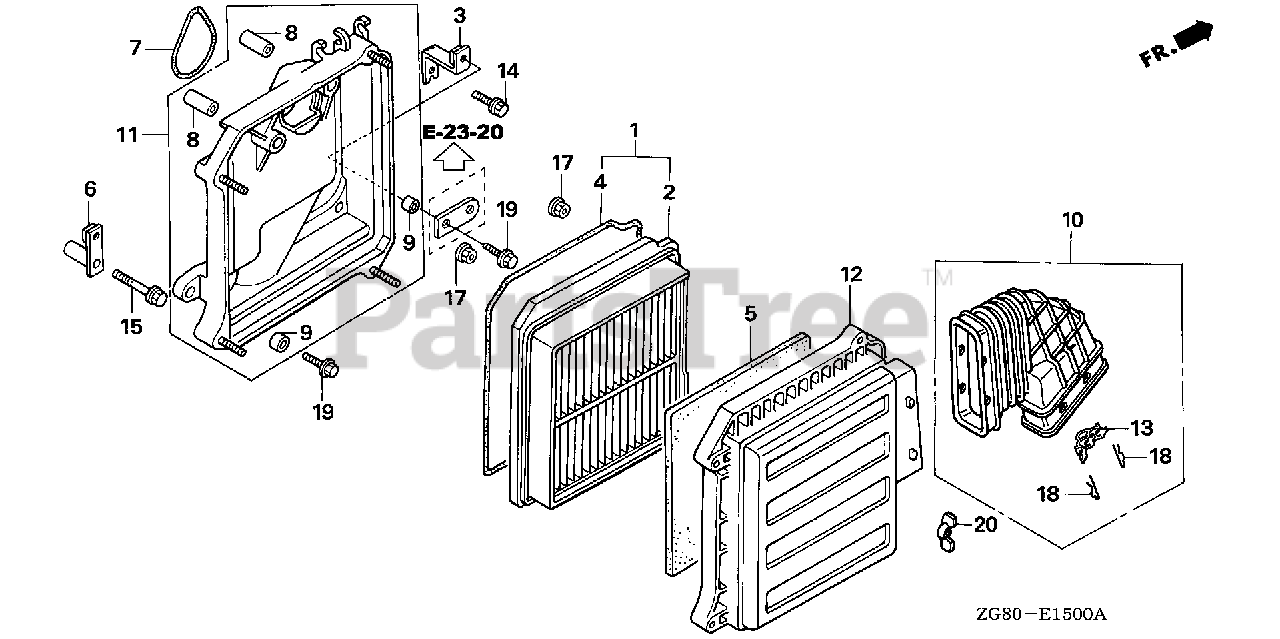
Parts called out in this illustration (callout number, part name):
1	ELEMENT KIT, AIR CLEANER
2	ELEMENT KIT, AIR CLEANER
3	BRACKET, R. AIR CLEANER
4	GASKET, ELEMENT
5	FILTER (OUTER)
6	BRACKET, L. AIR CLEANER
7	GASKET, AIR CLEANER
8	COLLAR, AIR CLEANER
9	COLLAR B, AIR CLEANER
10	TUBE, AIR IN.
11	CASE, MUFFLER
12	COVER, MUFFLER
13	CLIP, HARNESS
14	BOLT, FLANGE (6X14) (CT200)
15	BOLT, FLANGE (6X45) (CT200)
17	NUT, FLANGE (6MM)
18	PIN, LOCK (6MM)
19	BOLT, FLANGE (6X20)
20	NUT, TOOL BOX SETTING
